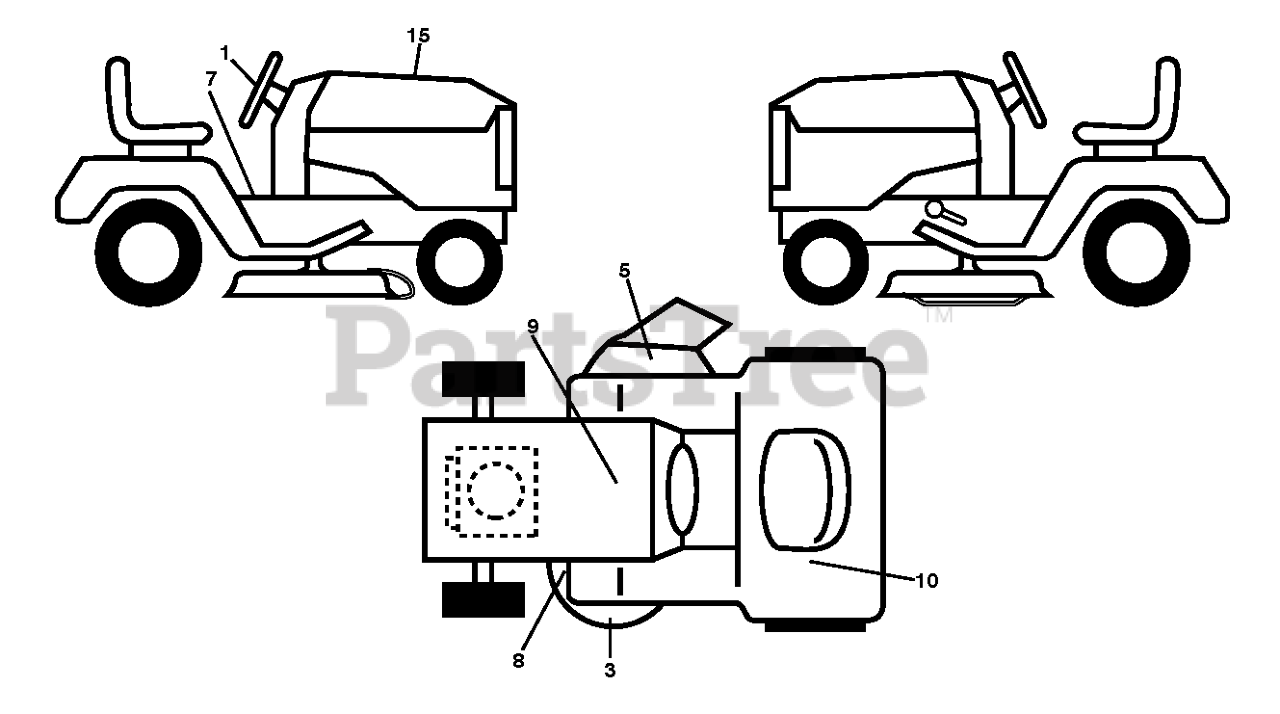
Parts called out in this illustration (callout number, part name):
1	DECAL STEERING WHEEL DECAL DEC
3	DECAL.DECK.CLEARCUT.NOSTEP
5	DECAL DECK WARNING GRAPHIC DEC
7	DECAL.FENDER.WARNING.ENGLISH
8	DECAL.V-BELT.SCH.42/46"MEC/ELE
9	DECAL BTRY SYMBOLS
10	DECAL.WARN.FUEL.RESERVE
15	DECAL.RPL.KW.FR6.TLB.42F.K46L
